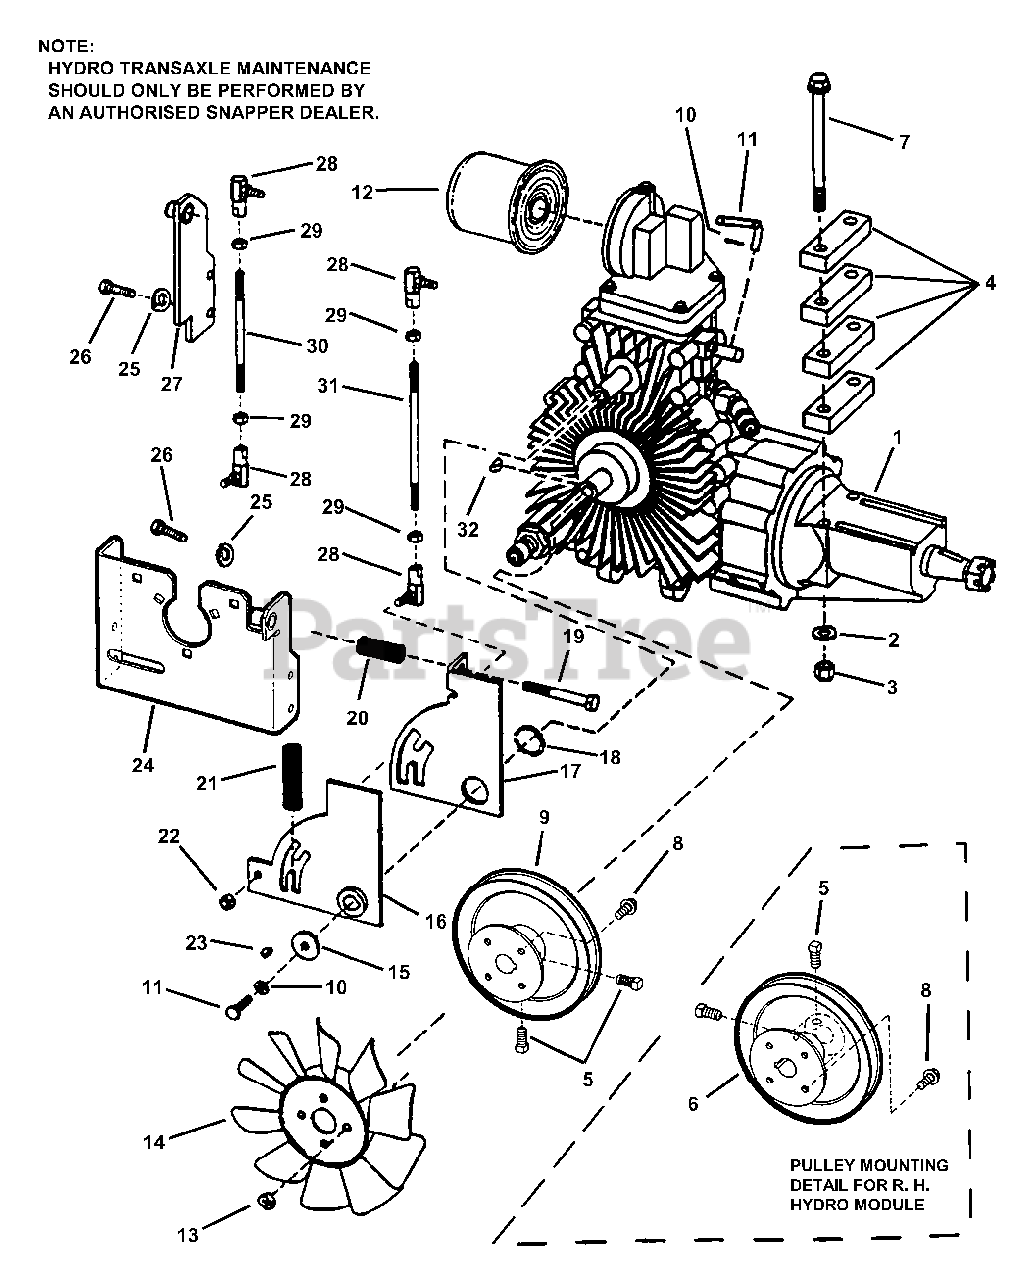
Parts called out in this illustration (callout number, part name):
1	ASS'Y, Eaton Transaxle 771B (L.H.) Side
2	WASHER, 3/8" Flat
3	NUT, 3/8-16 HEX NYLON LOCK
4	SPACER, Eaton Transaxle
5	SET SCREW, 5/16-18 x 5/16" Square Head
6	PULLEY, Transmission (Right Hand) 4.95" Diameter
7	BOLT, 3/8-16 x 4-3/4" Hex Flange, Grade 5
8	SCREW, 1/4-20 x 5/8", Hex Flange Lock, Grade 5
9	PULLEY, Transmission (Left Hand) 4.95" Diameter
10	WASHER, 1/4 Split Lock
11	SCREW, 1/4-20 x 1-1/4", Hex Head Cap
12	SCREW, 1/4-20 x 2", Hex Head Cap, Grade 5
13	NUT, 1/4-20 HEX NYLON LOCK
14	FAN, Blade 7" Dia.
15	WASHER, 1/4 I.D. x 1" O.D.
16	CAM, Neutral Return (Weldment)
17	PLATE, Neutral Adjust
18	RETAINING RING, 1" External
19	BOLT, 5/16-18 X 2-1/2" GD5 YZ
20	SPRING, Neutral Return Adjust
21	SPRING, Neutral Return
22	NUT, 1/4-28, Hex Nyloc
23	WOODRUFF KEY, #404
24	ASSEMBLY, Driveshaft Bracket
25	WASHER, 21/64" Split Lock
26	SCREW, 5/16-18 x 7/8", Hex Head Cap
27	PLATE, Neutral Return (Weldment)
28	BALL-JOINT 1/4-28 Thread
29	HN, 1/4F GR5 YZ
30	ROD, Threaded 1/4-28 x 6-5/8"
31	ROD, Threaded 1/4-28 x 5-3/8"
32	WOODRUFF KEY, #605
